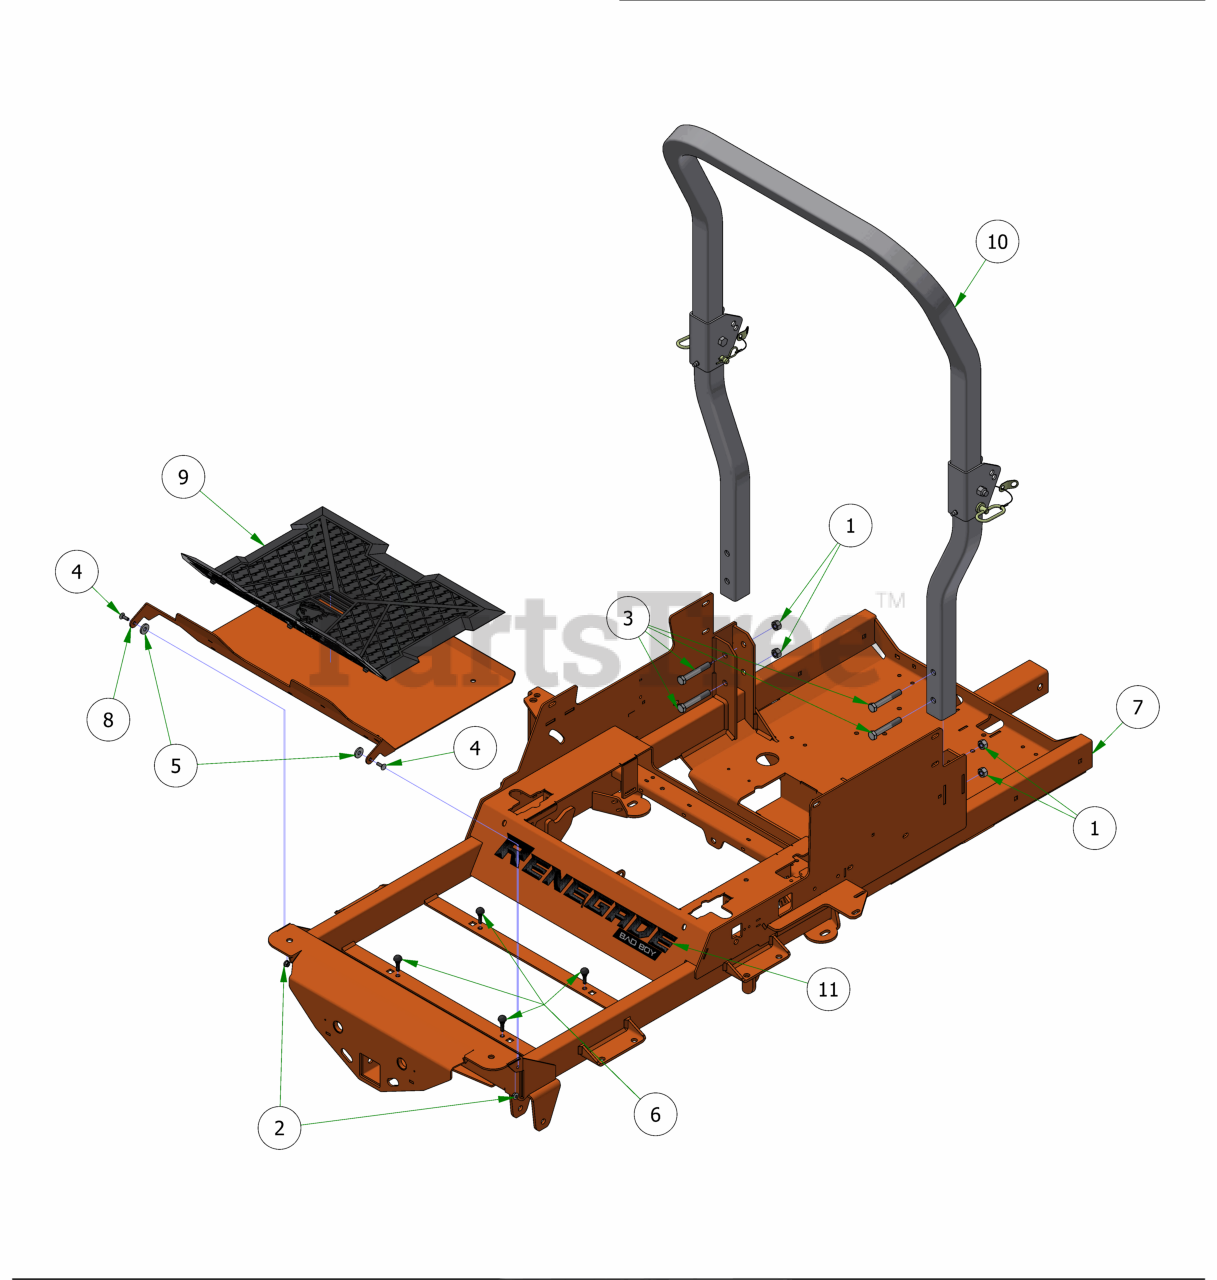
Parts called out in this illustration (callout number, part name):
1	1/2-13 HEX 2-WAY REVERSIBLE CENTER LOCKNUT Grade B ZINC
2	1/4-20 NYL INSERT FLANGE LOCKNUT ZINC
3	1/2-13 X 3-1/4 HEX CAP SCREW (GR.5) ZINC
4	1/4-20 X 3/4 CARRIAGE BOLT ZINC
5	.360 ID X .983 OD X .120 THICK FLAT WASHER NYLON
6	2023 Floor Board Rubber Bumper
7	2019 Renegade Gas Frame - Powdercoated
8	2024 R-Series Floorboard
9	24 R-Series Floorboard Matt v2
10	2019 2X2 Folding ROPS
11	Renegade Front Cover Decal
